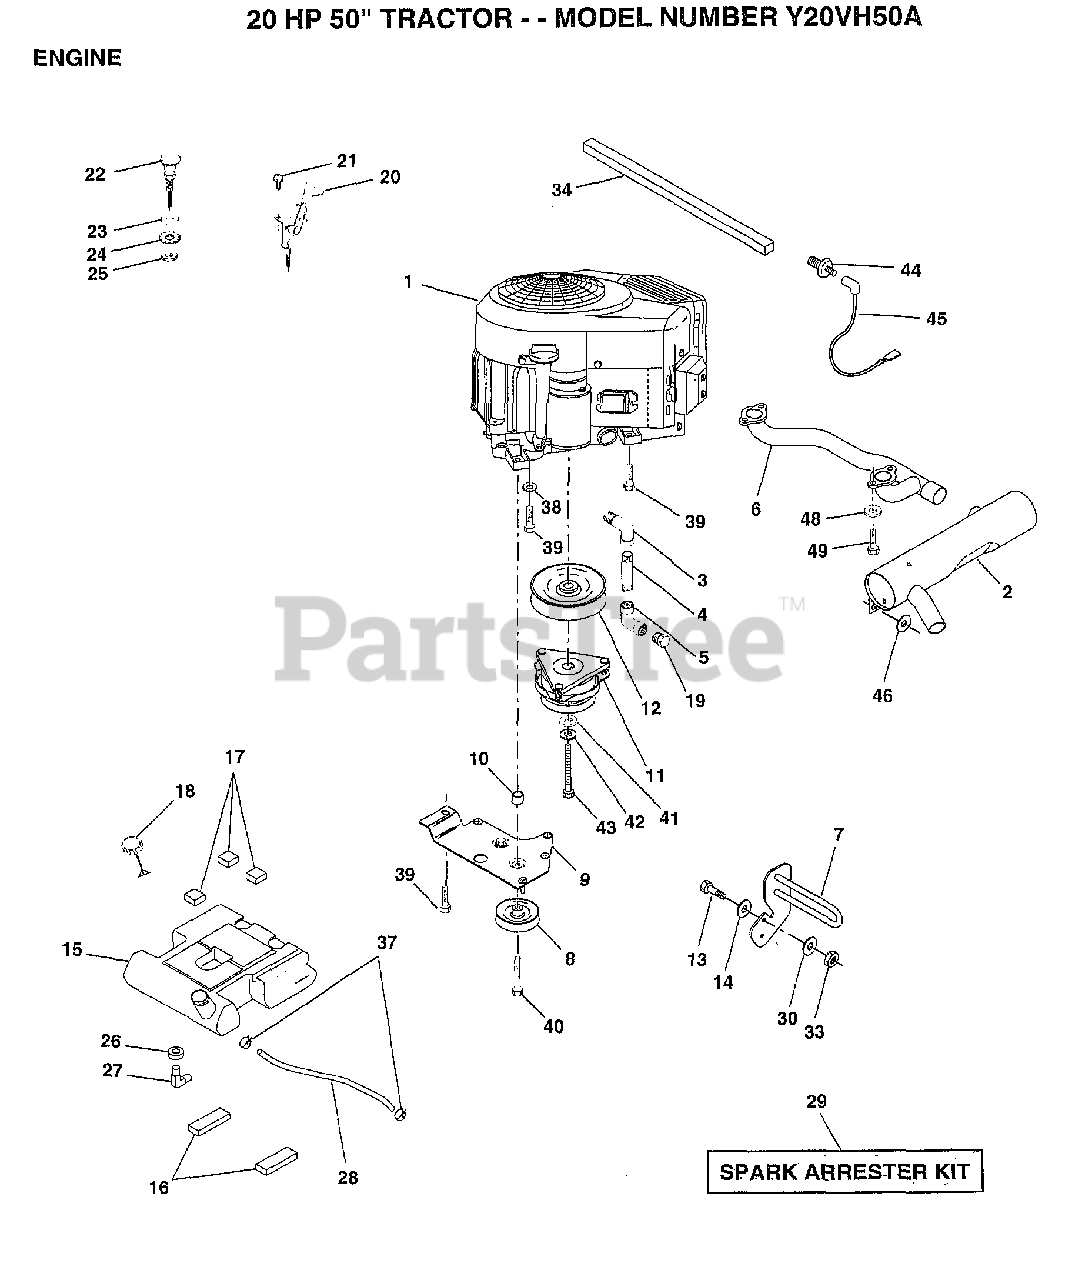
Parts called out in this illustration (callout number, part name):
3	STREET ELBOW LT
4	PIPE NIPPLE
5	ELBOW
6	PIPE.EXHAUST.B&S
10	BUSHING.
12	PULLEY.ENGINE.VGT
13	"BOLT,HEX"
14	WASHER
16	PAD IDLER TI
17	PAD-SPACER LT
18	CAP ASM FUEL
19	PLUG T
21	SCREW LT
23	WASHER
24	LOCKWASHER
26	BUSHING OUTLET T
27	STEM.TANK.FUEL
29	SPARK ARREST KIT
30	WASHER T
33	NUT
34	FOAM-STRIP LT
37	HOSE CLAMP
38	LOCKWASHER
39	SCREW LT
40	SCREW.3/8-16X3.25
41	WASHER
42	LOCKWASHER
44	SWITCH OIL KOHLER
45	WIRE.LEAD.SENTRY
46	WASHER HYT
48	LOCKWASHER
49	BOLT.HD.SOCKET.
